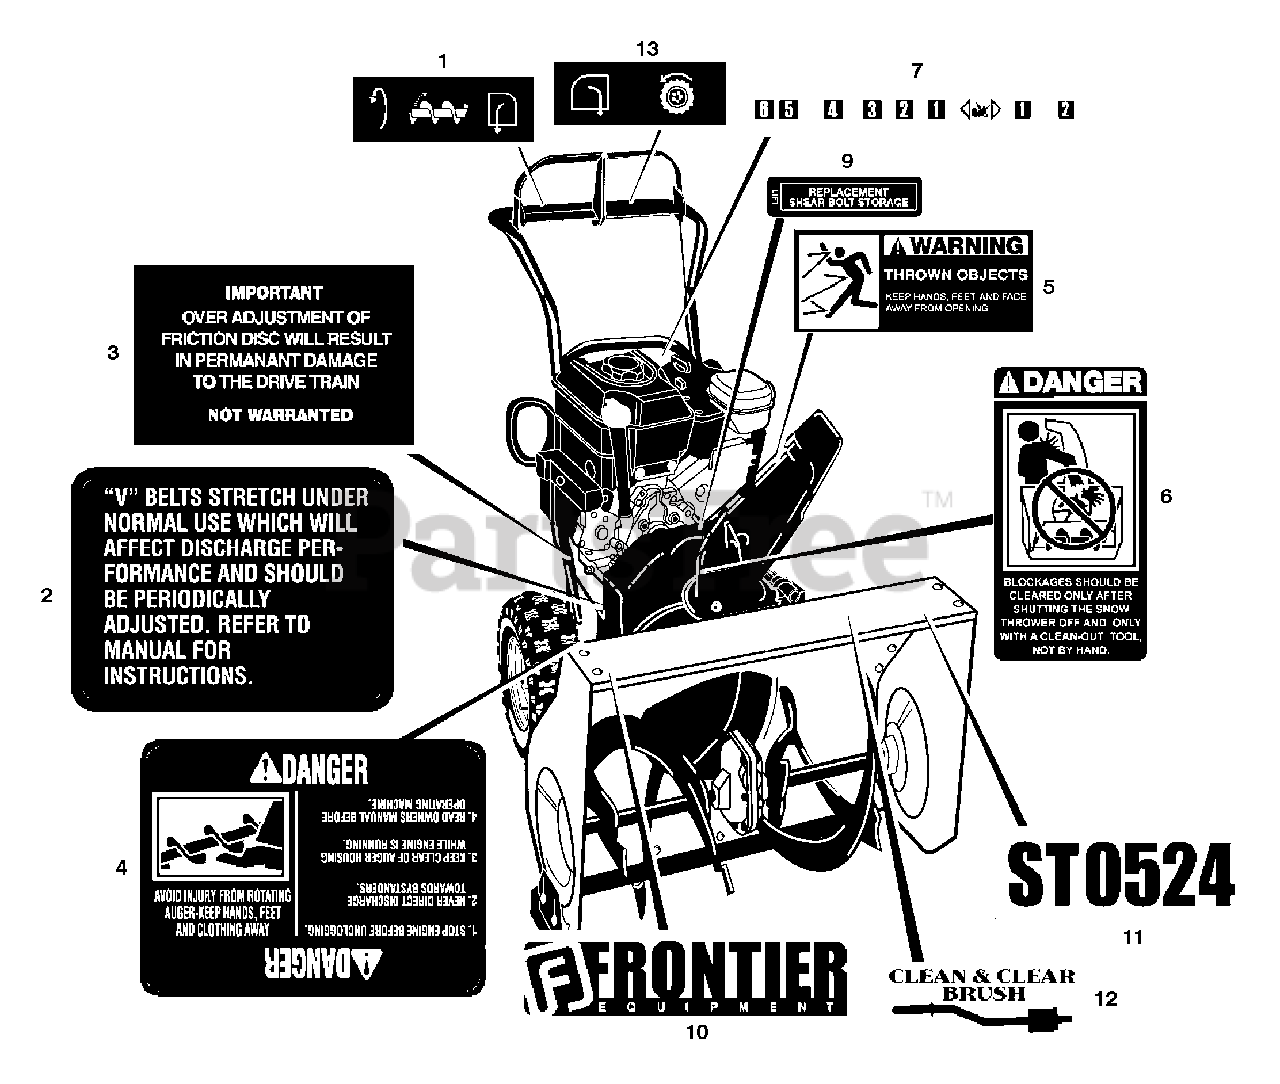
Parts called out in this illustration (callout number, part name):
1	DECAL, AUGER CONTROL
2	DECAL, V-BELTS
3	DECAL, OVER ADJUSTMENT
4	DECAL, ROTATING AUGER
5	DECAL, THROWN OBJECTS
6	DECAL, UNCLOGGING CHUTE
7	DECAL, SPEED CONTROL
9	DECAL, SHEAR BOLTS
10	LOGO, FRONTIER
11	DECAL, ST0524
12	DECAL, CLEAN & CLEAR BRUSH
13	DECAL, TRACTON CONTROL
